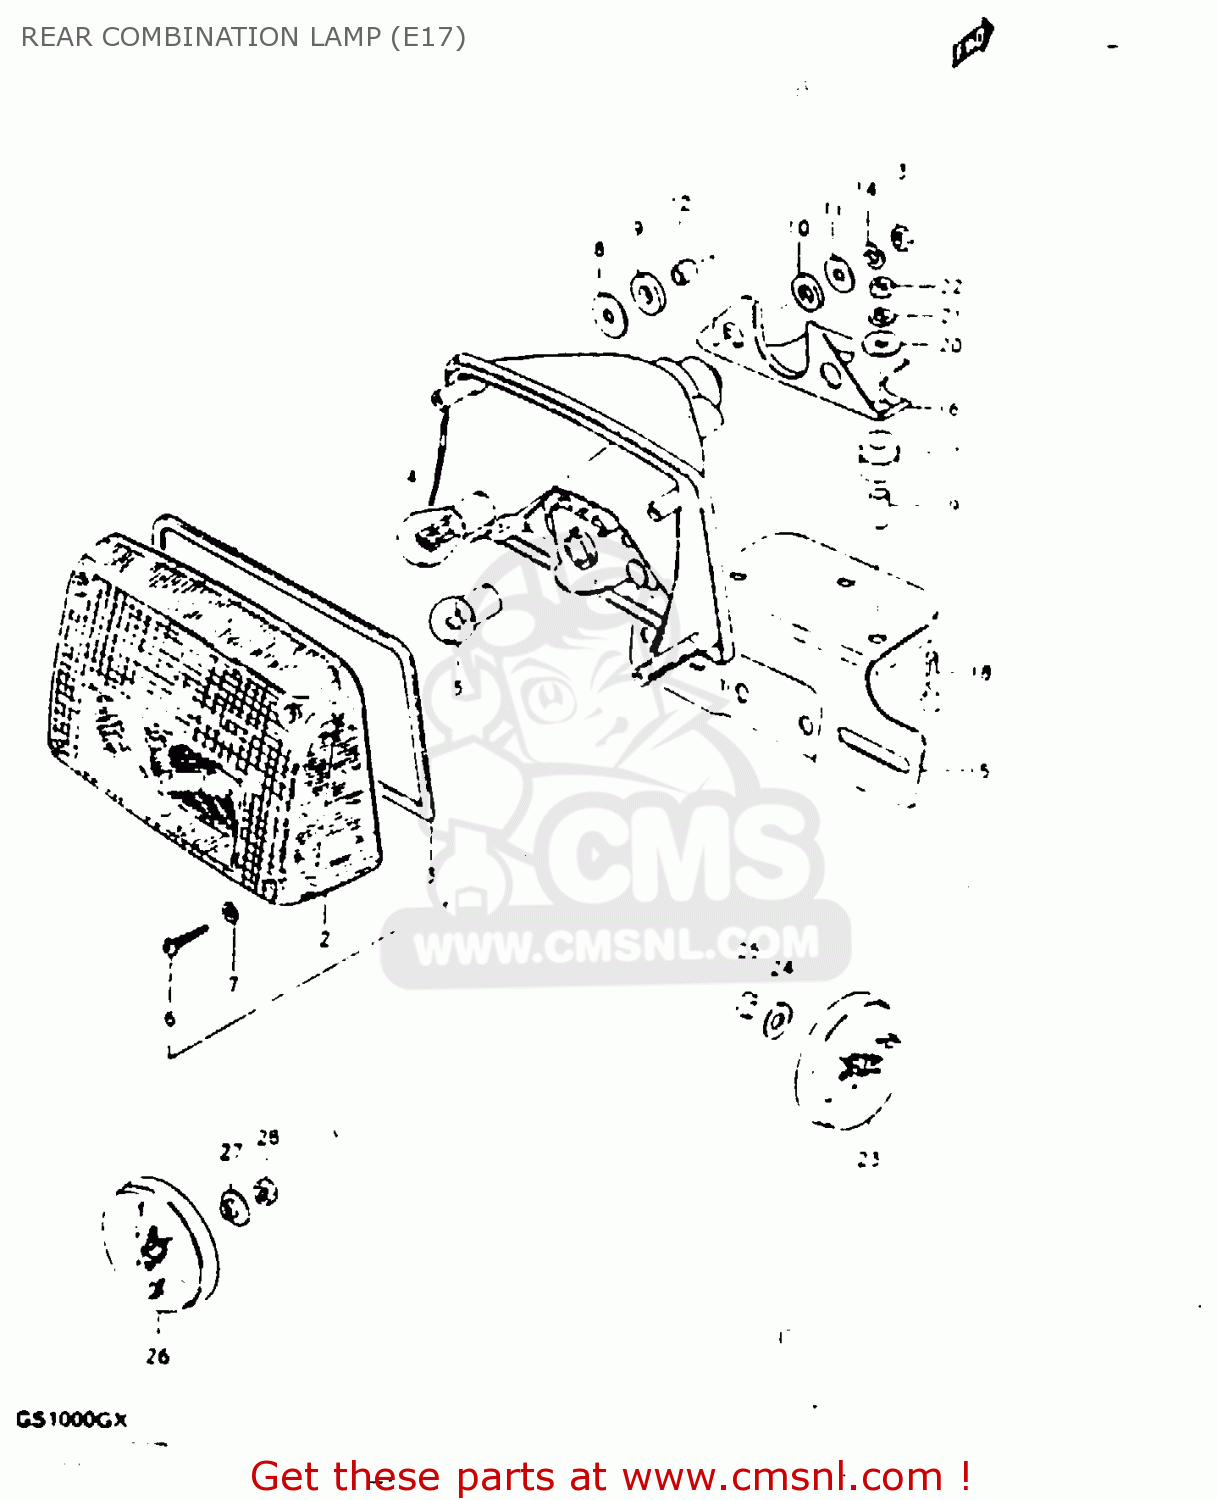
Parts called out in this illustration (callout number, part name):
1	LAMP, REAR COMBINATION
2	LENS
3	GASKET (NAS)
4	BULB 12V21/5W
5	BULB
6	BOLT
7	GASKET (NAS)
8	WASHER
9	CUSHION
10	CUSHION
11	WASHER(6,5X22X1.6)
12	SPACER(6.1X9X7.5)
13	NUT
14	LOCK WASHER
15	BRACKET, LICENCE PLATE
16	BRACKET,LICENSE PLATE
17	CUSHION, BRACKET
18	BOLT
19	SPACER (6.4X9X15.5)
20	WASHER
21	LOCK WASHER
22	NUT
23	REFLEX REFLECTOR,RR
24	WASHER
25	NUT
26	REFLEX REFLECTOR,RR
27	SPACER
28	NUT
